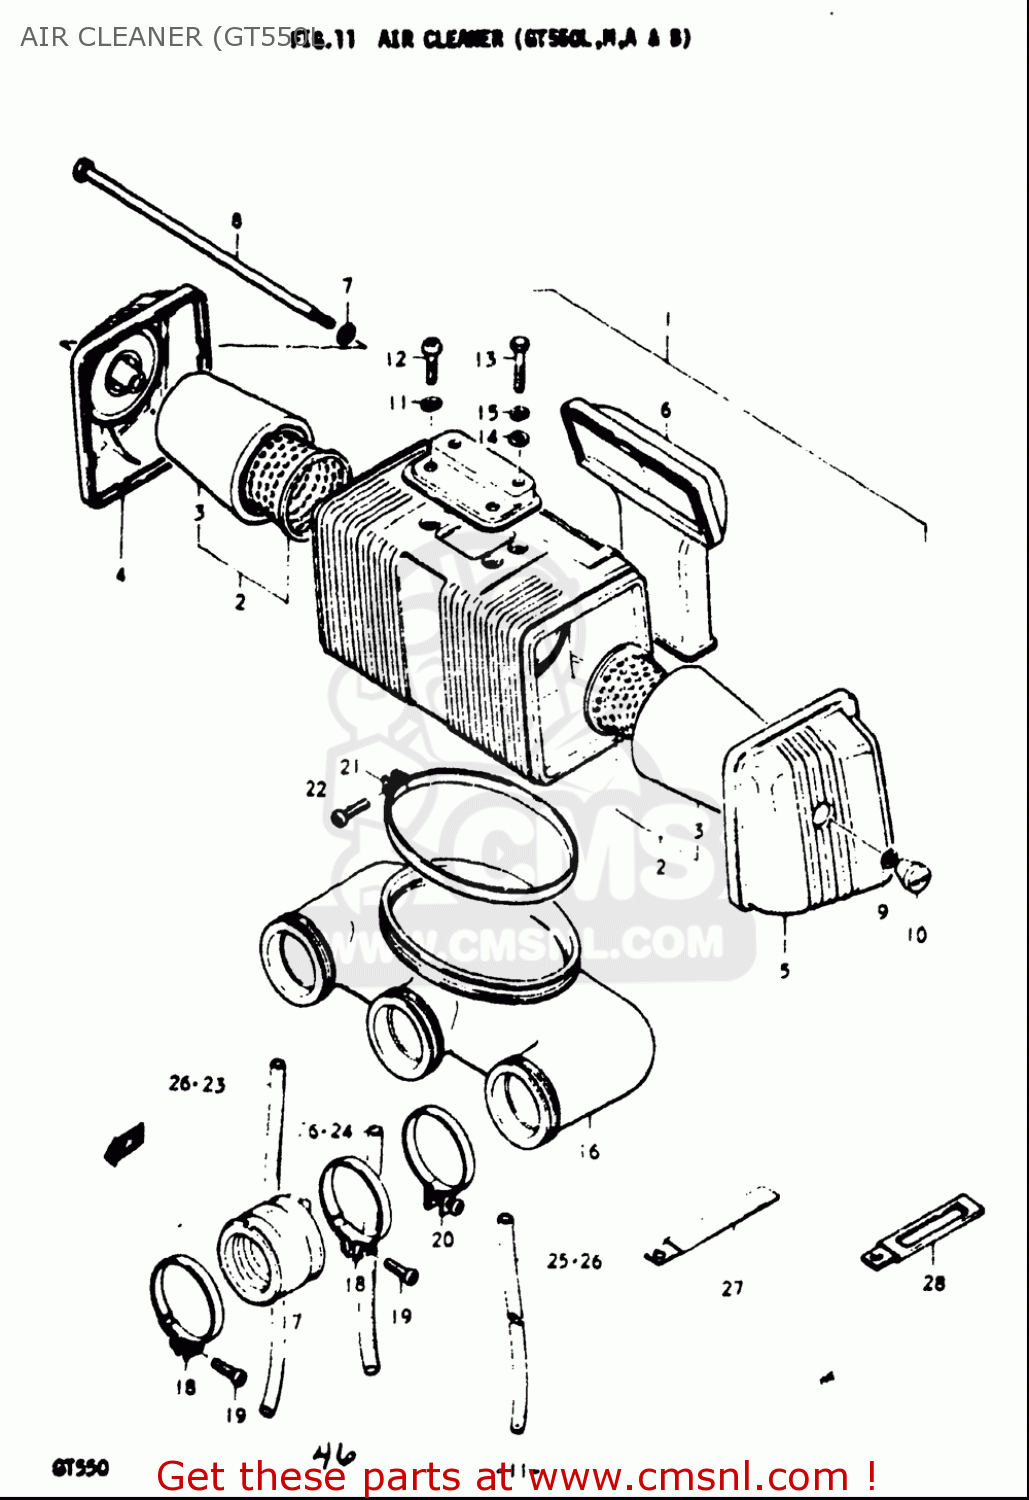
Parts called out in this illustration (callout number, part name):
2	FILTER ASSY,AIR CLEANER
3	FILTER ASSY,AIR CLEANER
9	WASHER
10	NUT,AIR CLEANER PLUG
11	WASHER,LOCK
12	SCREW
13	BOLT
14	WASHER(6.5X20X1.2)
15	WASHER,LOCK
17	PIPE,INTAKE
18	CLAMP
19	SCREW
20	CLAMP
22	SCREW
26	HOSE(3X5X600)
28	CLAMP(L:120 T:1.0)
